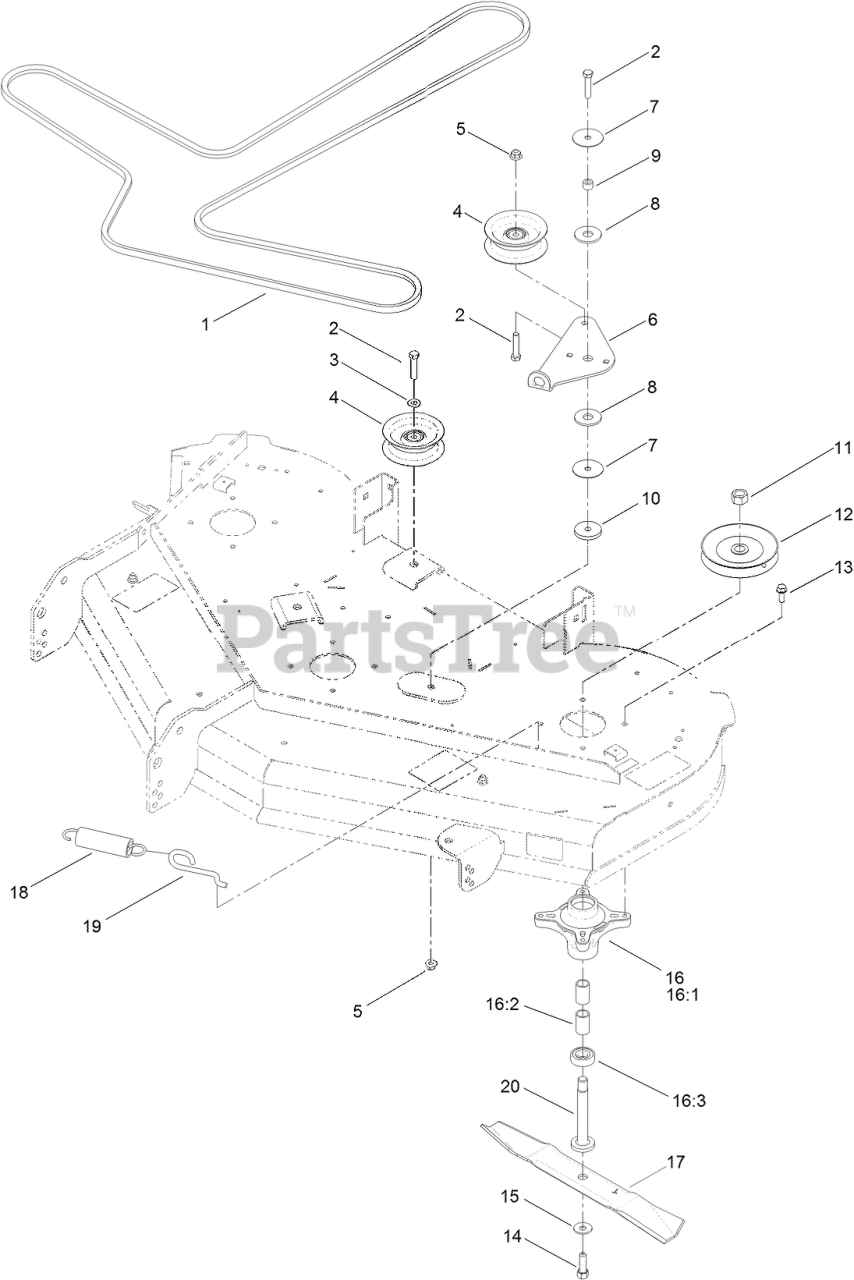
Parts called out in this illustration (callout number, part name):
1	V-BELT
2	SCREW-HH
3	WASHER-FLAT
4	PULLEY-IDLER, FLAT
5	NUT-HF, NI
6	ARM-IDLER
7	WASHER
8	WASHER-FRICTION, COMPOSITE
9	SPACER
10	WASHER-PLAIN
11	NUT-HEX
12	PULLEY
13	SCREW-TAPTITE
14	SCREW-HH
15	WASHER-BELLEVILLE
16	SPINDLE ASM
16:1	SPINDLE
16:2	SPACER
16:3	BEARING-BALL
17	BLADE-MULCH, 17.50 INCH
18	SPRING-EXTENSION
19	HOOK-RETURN, SPRING
20	SHAFT-SPINDLE
